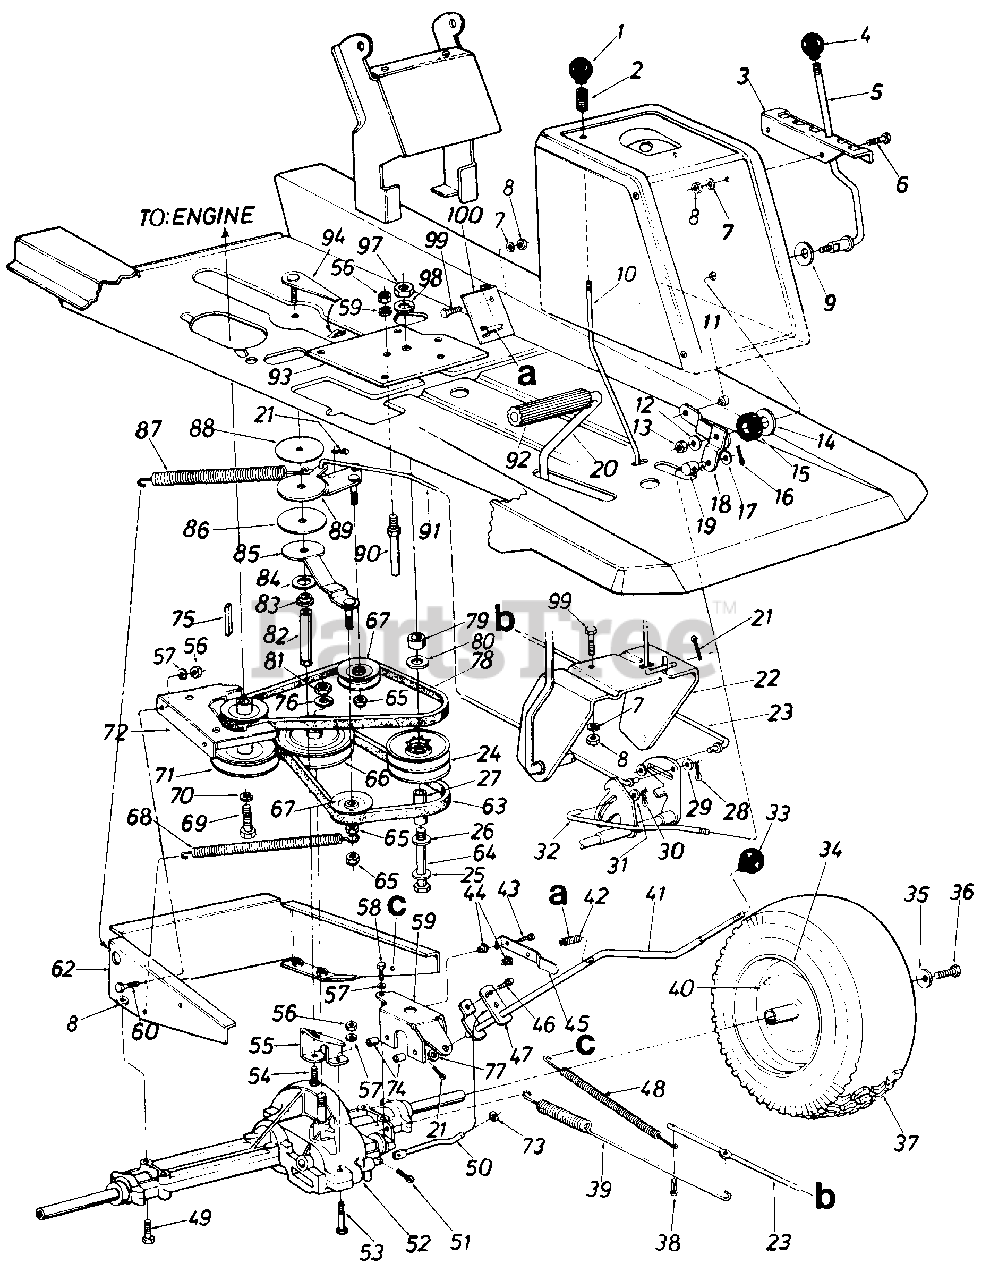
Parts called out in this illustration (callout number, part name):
1	Ball Knob 1/4-20 Thd. 1.25"
2	Compression Spring
5	Speed Control Lever
6	Truss Mach. Scr. 5/16-18 x .75" Lg.
7	L-Wash. 5/16" I.D.
8	Hex Nut 5/16-18 Thd.
9	Bell-Wash. .345" I.D. x .88"
10	Brake Locking Rod
12	Bell-Wash. .345" I.D. x .08"
13	Hex Cent. L-Nut 5/16-18 Thd.
14	Fl-Wash. .531" I.D. x 1.25" O.D.
15	Rubber Washer
16	Intern. Cotter Pin 1/2" Dia.
17	Fl-Wash. .34" I.D. x .68" O.D.
18	Speed Control Lever Brkt. Ass'y.
19	Ferrule-Engagement
20	Clutch/Brake Pedal Ass'y.
21	Cotter Pin 3/32" Dia. x .75"
22	Clutch/Brake Pedal Ass'y.
23	Brake Rod
24	Variable Speed Pulley Ass'y.
25	Washer .635" I.D. x 3.50" 0. D.
26	Thrust Brg. 1.25" O.D. x .56" I. D.
27	Spacer Sleeve 2.71"
28	Cotter Pin 1/8" Dia. x 1.25"
29	Fl-Wash. .34" I.D. x .60" O.D.
30	Intern. Cot-Pin 5/16" Dia.
31	Fl-Wash. .34" I.D. x .60" O.D.
32	Speed Control Rod
33	Ball Knob
34	Rear Wheel Rim Only
35	Bell-Wash. .345" I.D. x .88"
36	Hex L-Bolt 5/16-24 x .75" Lg.
37	Rear Wheel Ass'y.-Comp.
38	Cotter Pin 1/8" Dia. x 1.25"
39	Extension Spring 17.0" Lg.
40	Air Valve
43	C Sink AB S-Tap Scr. #8 x .50" Lg.
44	Push-in Nut #10
45	Spring Switch
46	Hex Bolt 1/4-20 x .50" Lg.
47	Shift Lever Adjusting Link
48	Ext. Spring 8-1/4" Lg.
49	3/16-18 x 2.50 Hex Bolt
50	Shift Rod
51	Intern. Cotter Pin
52	Transaxle
53	Hex Bolt 1/4-20 x 1.75" Lg.
54	Hex Bolt 3/8-24 x .751 Lg.
55	Torque Rod Bracket
56	Hex Nut 1/4-20 Thd.
57	L-Wash. 1/4" I.D.
58	Self-Tap Mach. Scr. Type "C" 1/4-20 x 1.37" Lg
59	Shift Lever Support Brkt.
60	Hex Bolt 1/4-20 x 1.00" Lg.
62	Transaxle Support Ass'y.
63	V-Belt
64	Hex Bolt 3/8-16 x 4.5" Lg.
65	Hex Ins. L-Nut 3/8-24 Thd.
66	5/8 V-Pulley .500" I.D. x 6"
67	V-Belt Idler .38" I.D. x 3.06"
68	Ext. Spring .50" O.D. x 6.37"
69	Hex Bolt 7/16-20 x 1.00" Lg.
70	L-Wash. 7/16" I.D.
71	Engine Pulley .500" O.D. & 3.56" O.D.
72	Upper Eng. Belt Guard
74	Spacer .256" I.D. x .50" O.D.
75	Sq.-Key 1/4" x 2.00" Lg.
76	L-Wash. 1/2" I.D.
77	Fl-Wash. .469" I.D. x .88" O.D.
78	V-Belt
79	Spacer 1.00" x .380" O.D.
80	Teflon Washer .565 I.D. x 1.12 O.D.
81	Hex Nut 1/2-20 Thd.
82	Torque Rod
83	Flange Bearing .378
84	Fl-Wash. .640" I.D. x 1.24"
85	Idler Bracket Ass'y.
86	Thrust Wash. .635" I.D.
87	Extension Spring 7.58" Lg.
88	Thrust Wash. .385" I.D.
89	Idler Bracket Ass'y. For Clutch
90	Belt Guard Pin 1/4" Dia.
91	Clutch Rod
92	Foot Pad
93	Mtg. Brkt. Variable Pulley
98	L-Wash. 3/8 Heavy Duty
99	Hex Bolt 5/16-18 x .75" Lg.
100	Shift Lever Spring Brkt.
